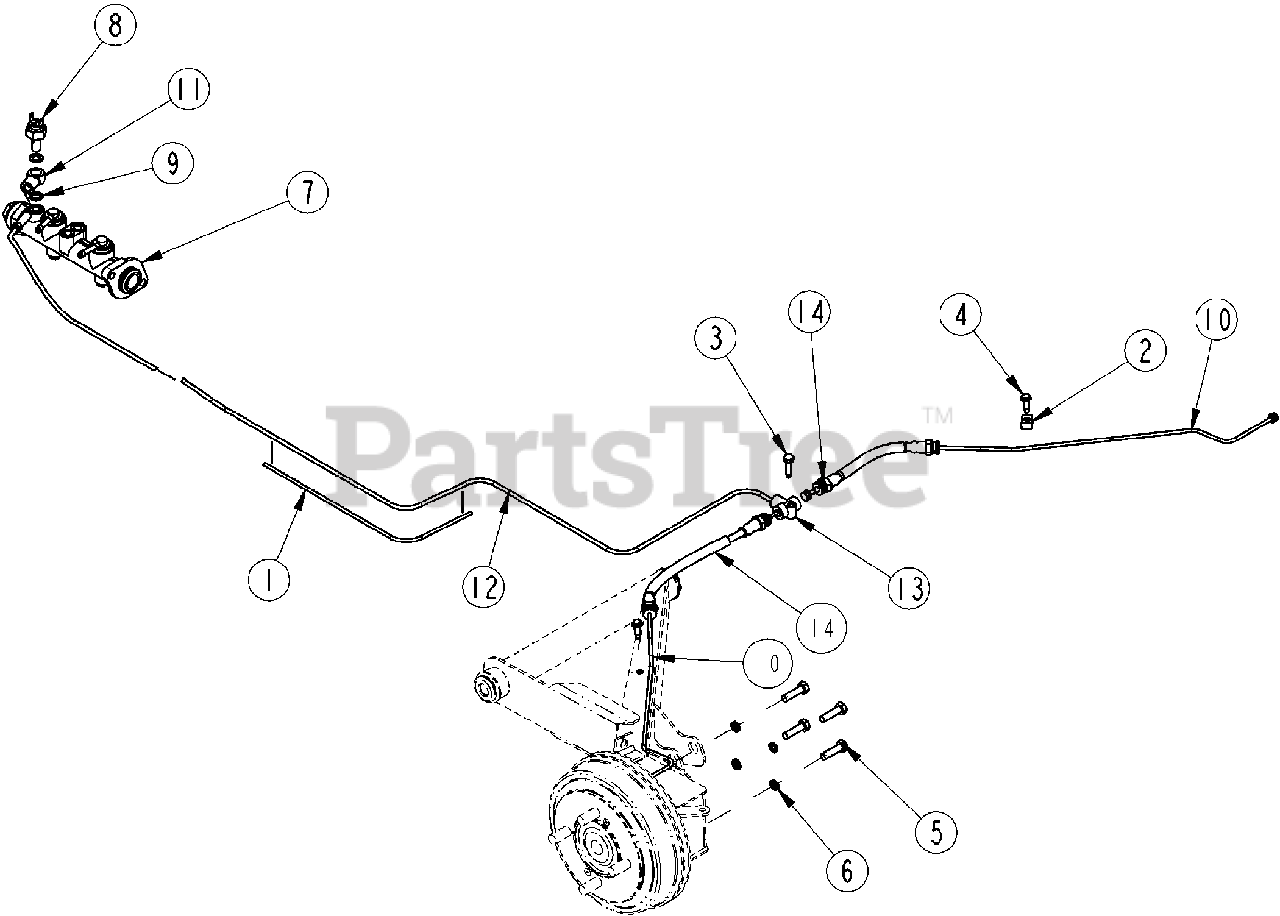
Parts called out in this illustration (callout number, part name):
1	COVER, BRAKE LINE 13.5"
2	WIRING/TUBE CLIP FOR 1/4 OD
3	SCR HEX SELF TAP 1/4-20X1TYPEF
4	HH DRILL SCREW 1/4 X 3/4LG
5	HHCS M8X1.25X30 GR10.9 ZNYCR
6	WASHER SPRING LOCK M8 PLT
7	DUAL MASTER CYLINDER
8	MASTER CYLINDER PRESS. SWITCH
9	MSTR CYL CPPR WSHR 16X10X1.5MM
10	REAR BRAKE LINE 28.3
11	BULK HEAD FLOW THROUGH
12	ST STEEL BRAKE LINE
13	FITTING 3 WAY HYD.
14	REAR RUBBER BRAKE LINE
